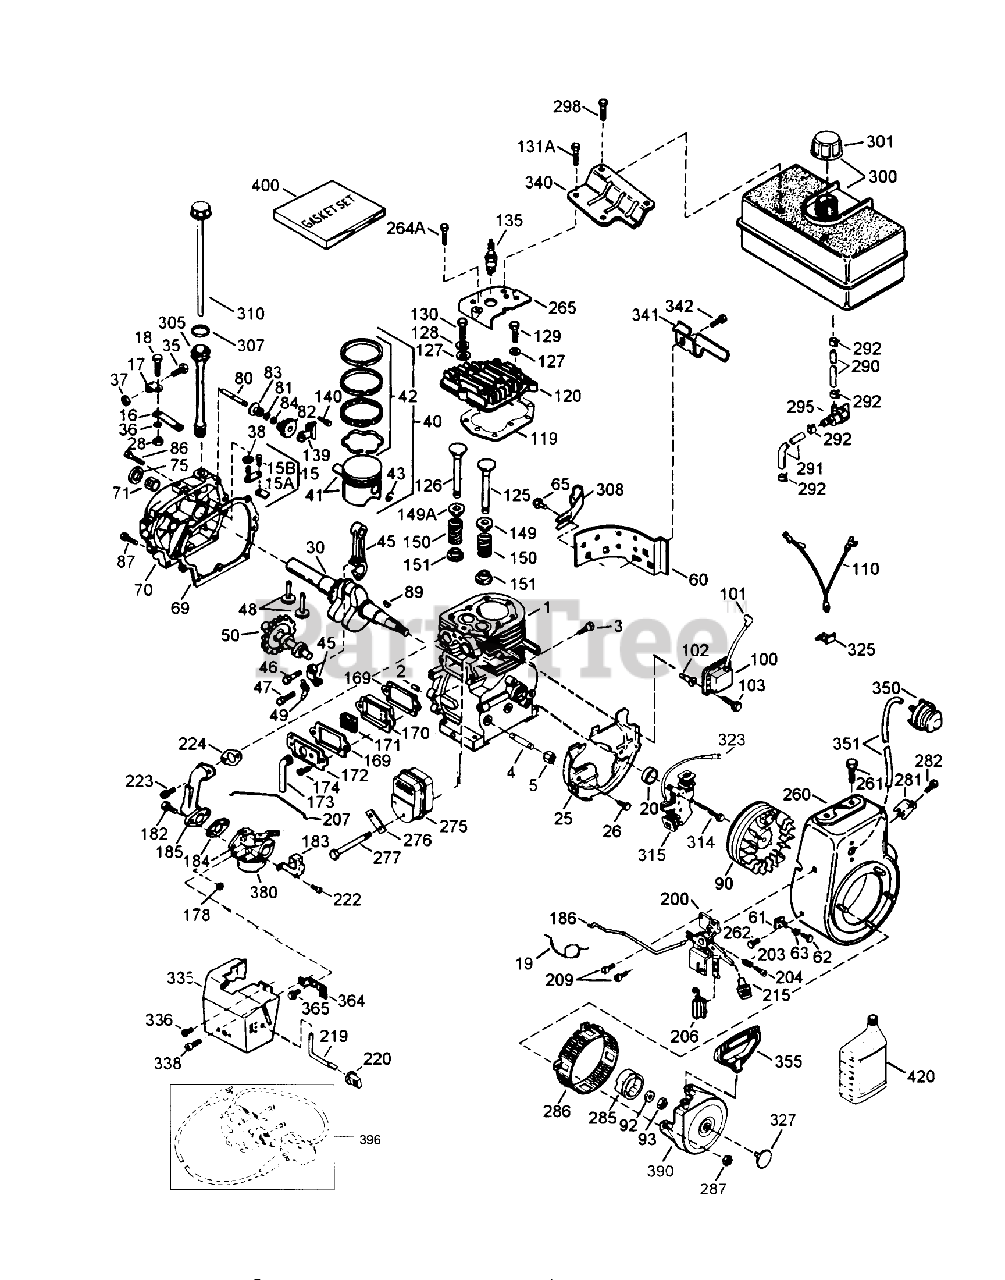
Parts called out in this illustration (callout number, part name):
1	Cylinder Asm (Includes 2, 20, 72)
2	Pin-Dowel
3	Screw (1/4-20x1/2)
4	Nipple-Pipe
5	Cap-Pipe
15	Rod, Governor (Incl. Nos.62 63)
15A	Yoke-Governor
15B	Screw (6-40x5/16)
16	Lever-Governor
17	Clamp-Lever, Governor
18	Screw
19	Spring-Throttle
20	Seal-Oil
25	Baffle-Housing, Blower
26	Screw (1/4-20x19/32)
28	Nut-Lock
30	Crankshaft
35	Screw
36	Washer-Lock
37	Nut-Lock
38	Ring-Retaining
40	Piston, Pin Ring Assy.(Std.) (Incl. Ref. #24A, 25 26)
40	Piston, Pin Ring Assy. (.010 oversize) (Incl. Ref. #24A, 25 26)
40	Piston, Pin Ring Assy. (.020 oversize) (Incl. Ref. #24A, 25 26)
41	Piston Pin Assy. (Std.) (Incl. Ref. #26)
41	Piston Pin Assy. (.010 oversize) (Incl. Ref. #26)
41	Piston Pin Assy. (.020 oversize) (Incl. Ref. #26)
42	Ring Set (Std.)
42	Ring Set (.010" OS)
42	Ring Set (.020" OS)
45	Rod Assy., Connecting (Incl. Ref. #28 28A)
46	Bolt-Rod
47	Bolt-Rod
48	Lifter-Valve
49	Dipper-Oil
50	Camshaft (MCR)
60	Extension-Housing, Blower
61	Bracket
62	Screw (8-32 x 3/8)
63	Grommet
65	Screw
69	Cylinder Cover Gasket
70	Cover-Cylinder (Includes 71, 75, 80)
71	2025A77 WIZARD ROTA
75	Seal-Oil
80	Shaft-Governor
81	Washer-Flat
82	Gear Assy., Governor (Incl. Ref. #45)
83	Spool-Governor
84	Ring-Retaining
86	Screw (1/4-20x1-3/16)
87	Screw (1/4-20x1-11/16)
89	Key-Flywheel
90	Flywheel ASM
92	Washer-Belleville
93	Nut-Flywheel
100	Solid State ASM
101	Cover-Spark Plug
103	Screw
110	Ground Wire
119	Gasket-Head, Cylinder
120	Head-Cylinder
125	Valve, Exhaust (Standard)(Incl. No. 9)
125	Valve, Exhaust (1/32" oversize)(Incl. No. 9)
126	Valve, Intake (Std.) (Incl. Ref. #58)
126	Valve, Intake (1/32" oversize) (Incl. Ref. #58)
127	Washer-Flat
129	Screw (5/16-18x1-25/32)
130B	Screw (5/16-18x1-1/2)
131A	Screw
135	Spark Plug-Resistor (R J19 L M)
139	Bracket-Gear, Governor
140	Screw (10-24x1/2)
149	Cap-Spring, Valve
149A	51106 GILSON ROTARY
150	Spring-Valve
151	Keeper-Spring, Valve
169	Gasket-Cover, Valve
170	Body-Breather
171	Element-Breather
172	Cover-Valve
173	Tube-Breather
174	Screw
178	Nut and Lock Washer (1/4-28)
182	Screw (1/4-28x1)
183	Bracket-Choke
184	Gasket-Carburetor To Intake Pipe
185	Pipe-Intake
186	Link-Governor
200	Bracket-Control (Includes 19, 203, 204, 206)
203	Spring-Compression
204	Screw
206	Terminal
207	Link-Throttle
209	Screw (10-32 x 1/2)
215	Knob-Control
219	Rod-Choke
220	Knob-Control
222	Screw (10-32 x 1/2)
223	Screw (T-30, 5/16-18x1-3/32)
224	Gasket-Pipe, Intake
260	Housing-Blower
261	Screw (5/16-18x3/4)
262	Screw
264A	Screw (1/2-20x5/8)
265	Cover-Cylinder Head
275	Muffler
276	62513 SNWTHWR W/284
277	Screw
281	Screw
282	Screw (8-32 x 3/8)
285	Hub-Starter
286	Screen-Starter
287	Nut and Lock Washer (1/4-28)
290	Line-Fuel (8.62)
291	Line-Fuel
292	Clamp-Line, Fuel
295	Valve-Shut Off, Fuel
298	Screw (1/4-15x7/8)
300	Tank-Fuel (Includes 292, 301)
301	Cap-Fuel
305	Tube-Fill, Oil
307	O-Ring
308	Clip-Tube, Fill
310	Gauge Oil ASM
314	Screw (1/4-20 x 3/4)
315	Coil-Alternator, 18 Watt (Includes 323)
323	Terminal
325	Clip-Wire
327	Plug Starter
335	Cover-Carburetor
336	Screw (10-32x1/2)
338	Screw (10-32 x 3/8)
340	Bracket-Tank, Fuel
341	Bracket-Tank, Fuel (Black)
342	Screw (1/4-20x19/32)
350	Primer-Asm
351	Line-Primer
355	Handle-Starter, Mitten Grip
364	Bracket-Carburetor
365	Screw (8-32x27/64)
380	Carburetor (Incl. Ref. #184)
390	Rewind Starter
396	Starter-Electric (110 Volt)
400	Gasket Set
420	Oil-Engine (SAE 5W30)
